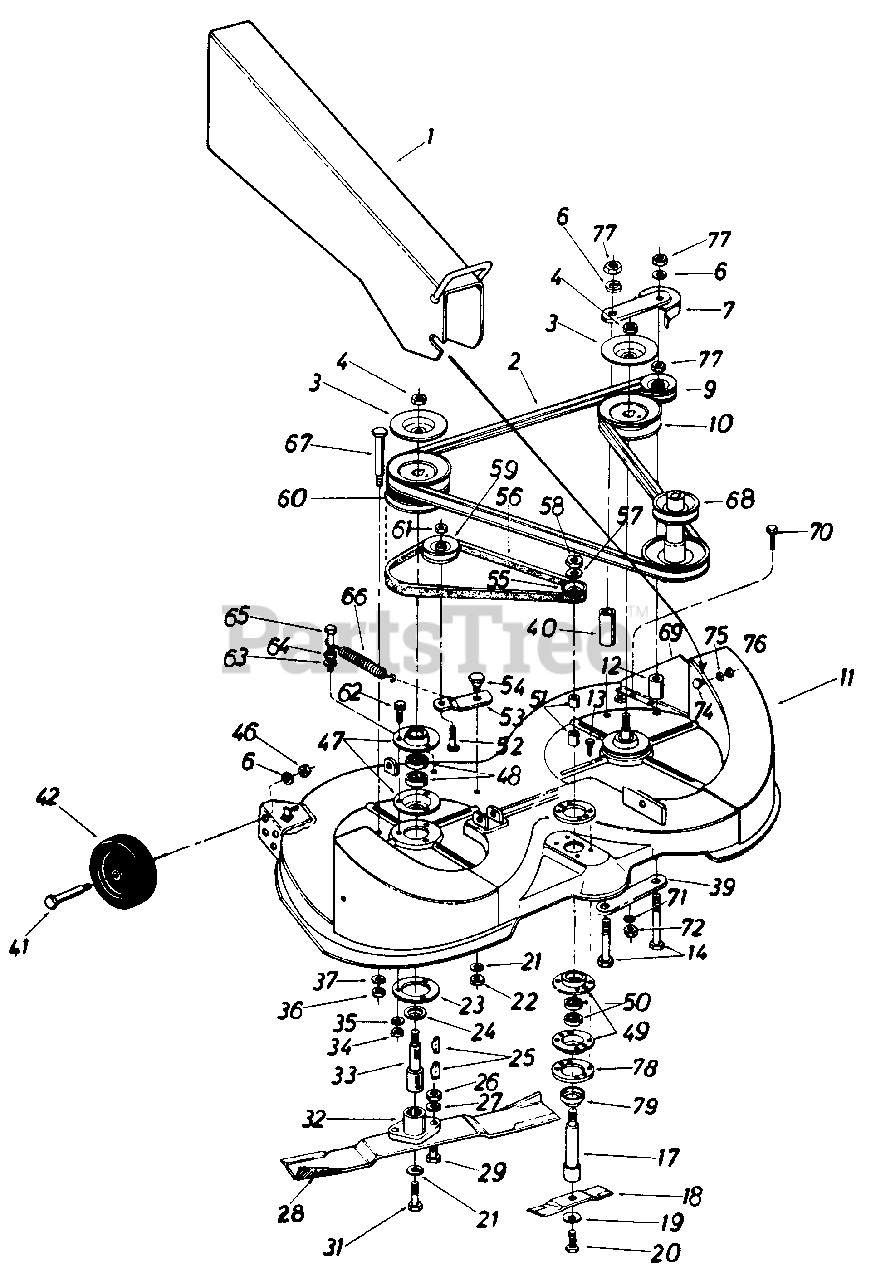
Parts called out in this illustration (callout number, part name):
1	Chute Extension Ass'y.-L.H.
2	"V"-Belt
3	Brake Disc
4	Hex Cent. L-Nut 5/8-11 Thd.
6	L-Wash. 3/8" I.D.
7	Idler Pulley Belt Guard Ass'y.
9	5/8-V Belt Idler 3.50" O.D.
10	5/8-V Pulley-.628" I.D. x 5.25" O.D.
11	40 Rear Discharge Deck
12	Spacer .40" I.D. x 1.25" O.D. x 1.59" Lg.
13	Hex B-Tap Scr. 1/4" x 1.0"
14	Hex Bolt 3/8-24 x 3.75" Lg.
17	Blade Spindle
18	6.50" Blade
19	Bell-Wash. .40" I.D. x .88" O.D.
20	Hex Bolt 3/8-24 x .87n Lg.
21	L-Wash. 3/8" I.D.
22	Hex L-Nut 3/8-16 Thd.
23	Plate-Deck Reinforcement
24	Bearing Shield
25	#6 Hi-Pro Key 5/32 x 5/8" Dia.
26	Hex Nut 5/16-24 Thd.
27	L-Wash. 5/1 6" I.D.
28	20" High Lift Blade-R.H.
29	Hex Bolt 5/16-24 x 1.00" Lg.(Grade 5)
31	Hex Bolt 3/8-24 x 1.50" Lg.(Grade 5)
32	Blade Adapter Kit
33	Blade Spindle
34	Hex Nut 5/16-18 Thd.
35	L-Wash. 5/16" I.D.
36	Hex L-Nut 3/8-16 Thd.
37	L-Wash. 3/8" I.D.
39	Reinforcement Plate
40	Spacer 3/8" I.D. x .50" O.D. x 2.72"
41	Shld. Bolt .498" Dia. x 1.53" Lg.
42	Cutting Deck Wheel
46	Hex Jam Nut 3/8-16 Thd.
47	Bearing Housing
48	Ball Bearing .787" I.D. x 1.85" O.D.
49	Bearing Housing
50	Ball Bearing .63" I.D. x 1.38" O.D.
51	Spacer .63" I.D. x .88" O.D. x .57" Lg
52	Hex Bolt 3/8-16 x 1.25" Lg.
53	Idler Bracket
54	Shld. Bolt .625" Dia. x .170" Lg.
55	3/8n V-Pulley .628" I.D. x 200" OD
56	"V"-Belt
57	Bell-Wash. .63" I.D. x 1.05" O.D.
58	Hex Jam Nut 5/8-11 Thd.
59	1/2" V-Belt Idler 2.625" O.D.
60	Double Pulley
61	Hex Top L-Jam Nut 3/8-16 Thd.
62	Hex Sems Bolt 5/16-18 x 1.00" Lg .
63	L-Wash. 1/4" I.D.
64	Hex Nut 1/4-20 Thd.
65	Hex Bolt 1/4-20 x l.00" Lg.
66	Ext. Spring .50" O.D. x 3.97" Lg
67	Shld. Bolt .498n Dia. x 2.63" Lg.
68	Two Step Engine Pulley
69	Inner Chute Extension-L.H.
70	Hex Sems Scr. 1/4-28 x .62" Lg.
71	L-Wash. 1/4" I.D.
72	Hex Nut 1/4-28 Thd.
74	Shld. Scr. .500" Dia. x .218
75	L-Wash. 3/8" I.D.
76	Hex Jam Nut 3/8-16 Thd.
77	Hex Nut 3/8-24 Thd.
78	Reintorcement Plate
79	Bearing Shield
